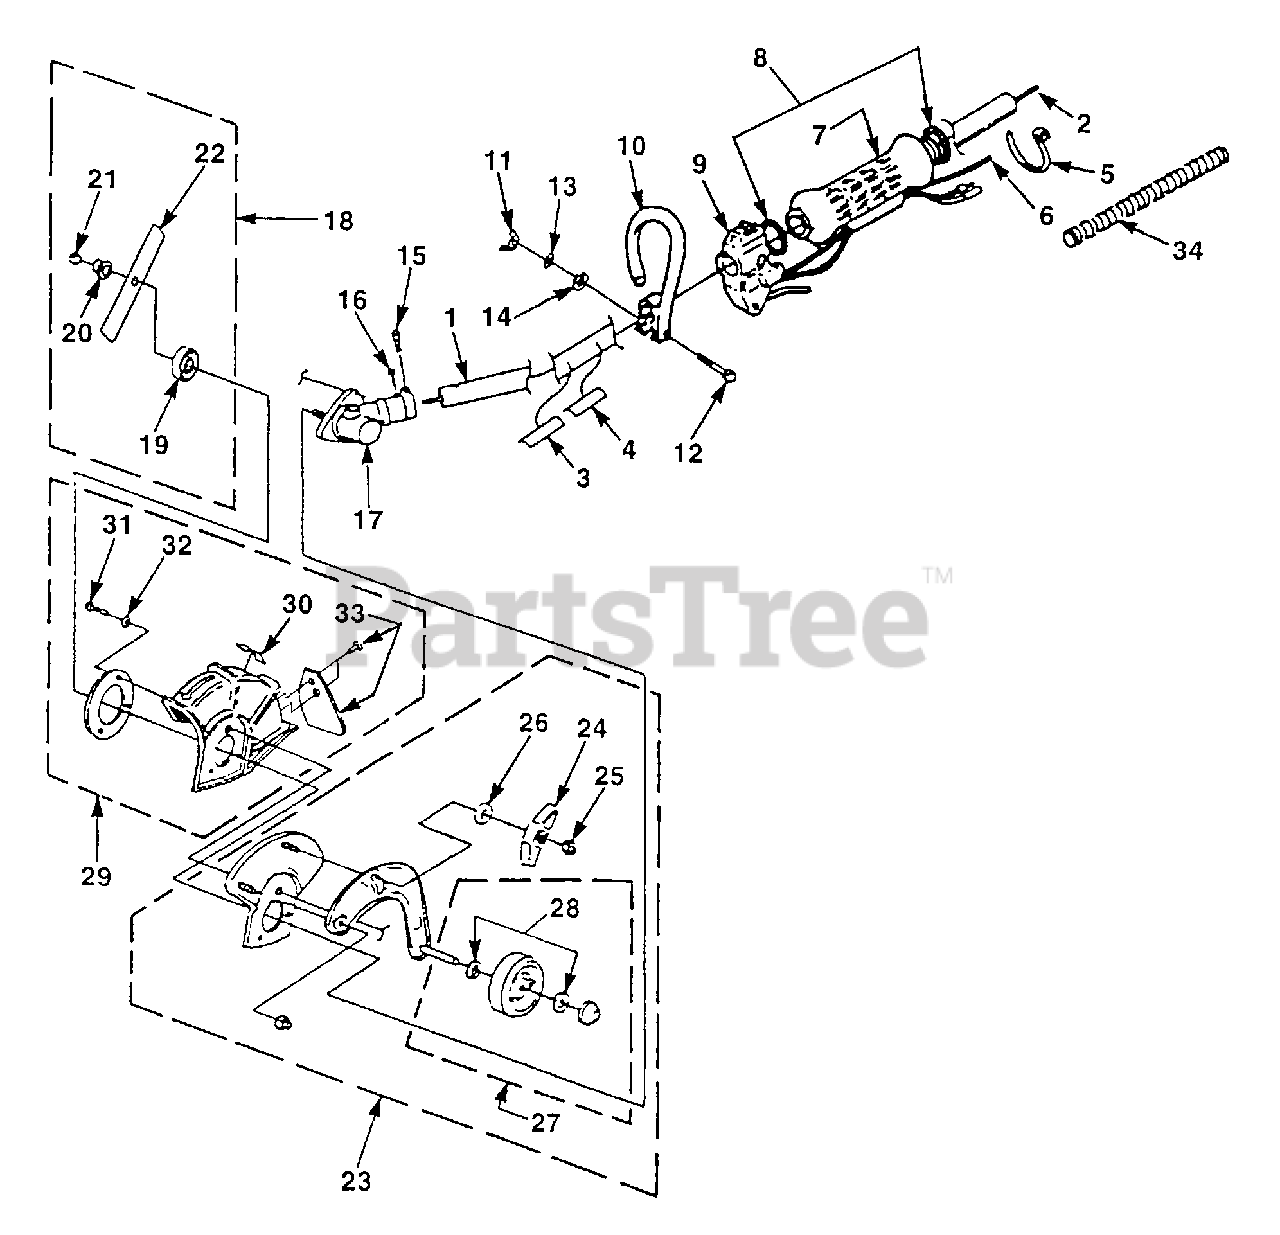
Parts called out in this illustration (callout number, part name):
1	DRIVESHAFT HOUSING
2	SHAFT-Flexible
3	DECAL-Warning
4	DECAL-Start Inst.
5	TIE-Cable
6	THROTTLE CABLE
7	HANDLE GRIP KIT
8	SPRING-Tension
9	THROTTLE & SWITCH
10	HANDLE-Front
11	NUT-Wing
12	SCREW-Cap Hex Hd (1/4-20 X 2")
13	WASHER-Lock
14	WASHER-Flat
15	SCREW-Cap Socket Hd (1/4-20 X 7/8")
16	SCREW-Sems Hex Hd (10-24 X 1/2")
17	GEAR HEAD
18	BLADE KIT
19	WASHER-Flanged
20	WASHER-Flanged (Lower)
21	NUT-Lock
22	BLADE, 2" X 9" (Qty 2)
23	SUPPORT ARM ASSEMBLY
24	KNOB-Adjusting
25	NUT-Hex
26	WASHER-Flat
27	WHEEL KIT
28	WASHER-Flat
29	GUARD KIT
30	DECAL-Warning
31	SCREW-Hex Hd (10-24 X 5/8")
32	WASHER-Lock (#10)
33	FLAP KIT
34	SLEEVING (Cut length to 10")
